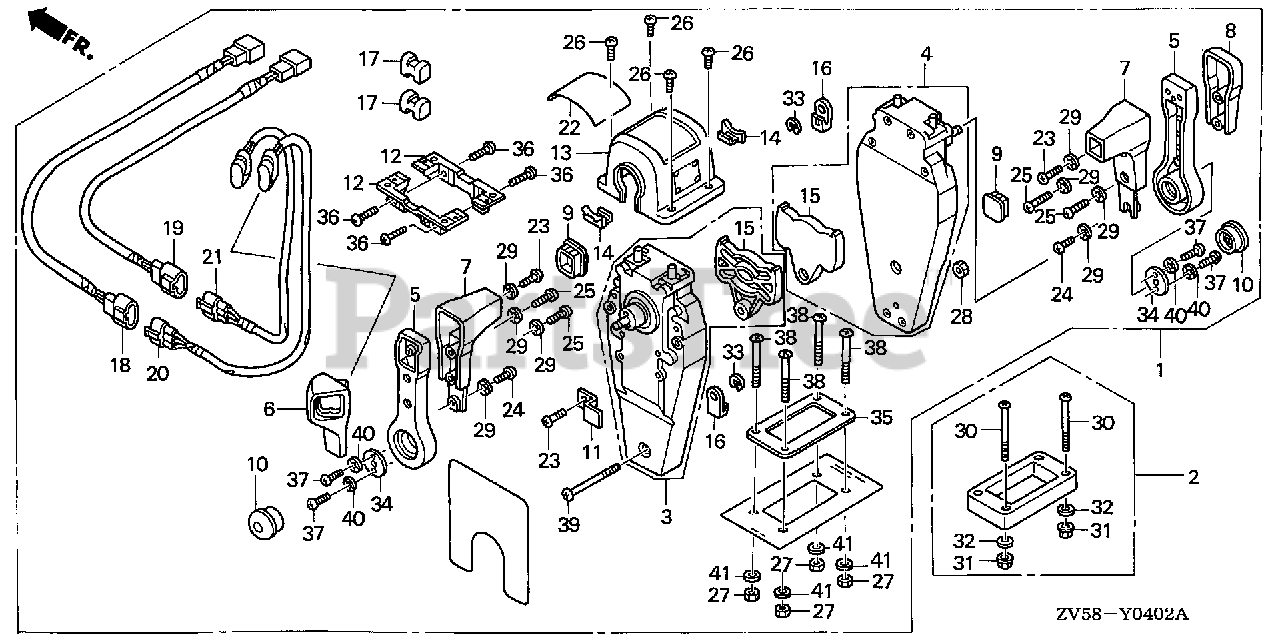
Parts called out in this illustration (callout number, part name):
1	BOX KIT, R. REMOTE CONTROL (TOP MOUNT DUAL)
2	SPACER KIT, REMOTE CONTROL BOX (TOP MOUNT DUAL)
3	HOUSING ASSY., L. (INNER) (TOP MOUNT)
4	HOUSING ASSY., R. (INNER) (TOP MOUNT)
5	HANDLE, REMOTE CONTROL
6	COVER, L. GRIP
7	GRIP, REMOTE CONTROL HANDLE
8	COVER, DUAL GRIP
9	CAP, GRIP
10	BUTTON, THROTTLE
11	PLATE, CABLE CLAMP
12	BRACKET, REMOTE CONTROL HOUSING
13	HOUSING, DUAL REMOTE CONTROL BOX
14	HOUSING, LEAD
15	PLATE, DWELL
16	TERMINAL, CABLE
17	SPACER, CABLE CLAMP
18	SUB-HARNESS ASSY., POWER TRIM-TILT (A)
19	SUB-HARNESS ASSY., POWER TRIM-TILT (B)
20	SWITCH ASSY., POWER TRIM-TILT (A)
21	SWITCH ASSY., POWER TRIM-TILT
22	MARK, REMOTE CONTROL (DUAL)
23	SCREW, PAN (5X16)
24	SCREW, PAN (5X10)
25	SCREW, PAN (5X20)
26	SCREW, PAN (4X10)
27	NUT, HEX. (5MM)
28	NUT, HEX. (5MM)
29	WASHER, LOCK (5MM)
30	SCREW, PAN (5X65)
31	NUT, FLANGE (5MM)
32	WASHER, PLAIN (5MM)
33	E-RING (6MM)
34	PLATE, HANDLE
35	GASKET, DUAL
36	SCREW, PAN (5X18)
37	SCREW, PAN (6X18)
38	SCREW, PAN (5X40)
39	SCREW, PAN (5X55)
40	WASHER, LOCK (6MM)
41	WASHER, PLAIN (5MM)
